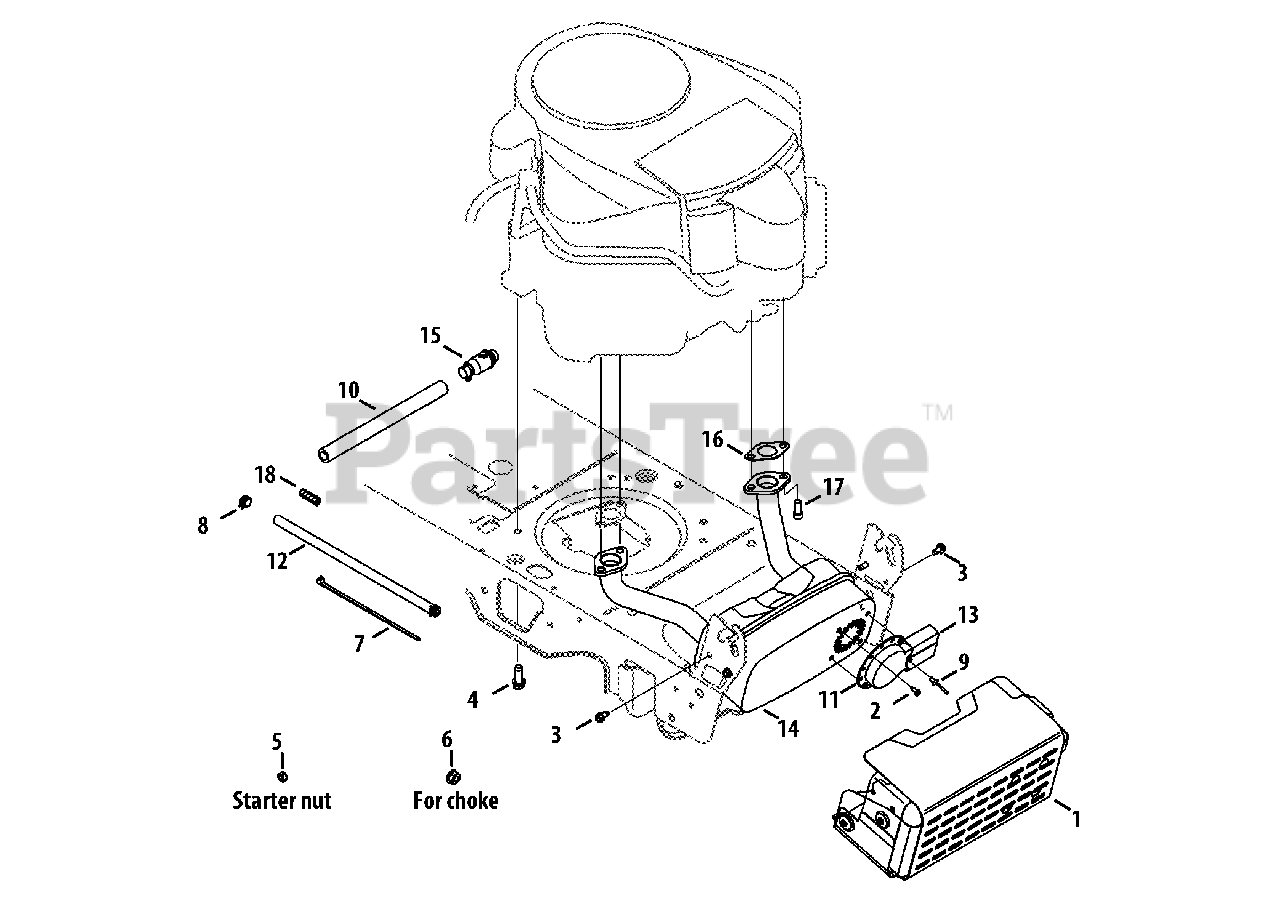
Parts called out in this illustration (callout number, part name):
1	Shield Ass’y, Muffler
2	Screw, Ab, #8-18, 0.500,
3	Screw, Self-tapping, 1/4-20, 0.500,
4	Screw, Self-tapping, 3/8-16, 1.0 Koh.
5	Nut, Sems, 1/4-20
6	Nut, Flange Lock, 3/8-16 Kaw.
7	Cable, Tie, 3/16 x .05 x 7.4
8	Clamp, Hose, .490 Dia.
9	Rivet, Pop, .188 Dia x .300
10	Hose, Extension, Oil Drain
11	Deflector, Muffler Koh.
12	Hose, Fuel, Low Permeation, 1/4
13	Deflector, Muffler, Long
14	Muffler, Kohler
15	Drain, Oil Koh.
16	Gasket, Exhaust, Koh.
17	Screw, Sokt Head, 5/16-18, .750 Koh.
